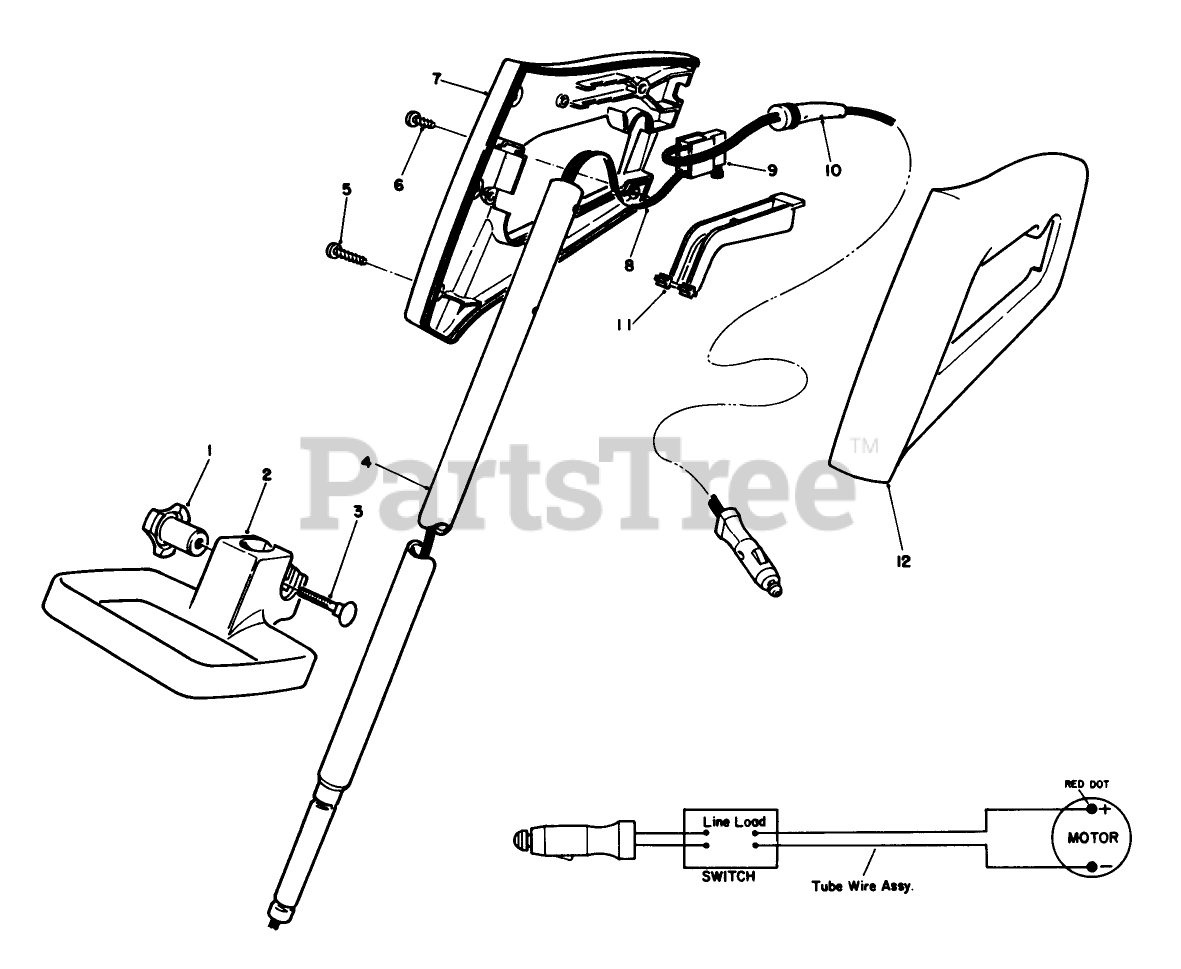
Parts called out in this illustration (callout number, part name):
3	BOLT-CARR
6	SCREW-PPH
11	TRIMMER-SWITCH BAR
